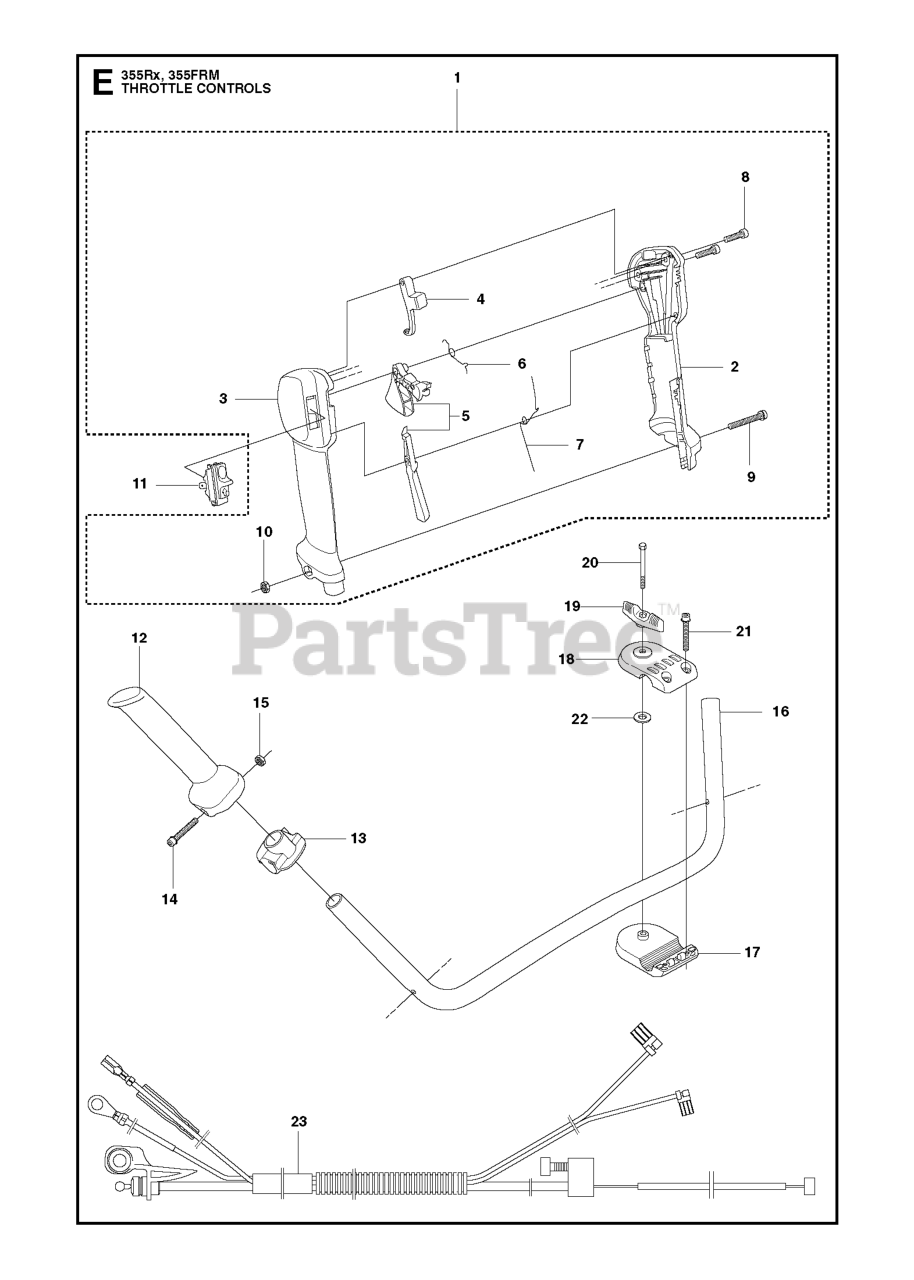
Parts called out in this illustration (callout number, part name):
1	THROTTLE HANDLE ASSY
2	HANDLE HALF RIGHT
3	HANDLE HALF LEFT
4	LOCKOUT STARTER THROTTLE
5	THROTTLE CONTROL
9	SCREW
11	STOP BUTTON
15	NUT M6M M5
16	HANDLE
17	HANDLE HOLDER LOWER
18	HANDLE HOLDER UPPER
20	%SCREW
23	WIRING ASSY SKOG
23	WIRING
